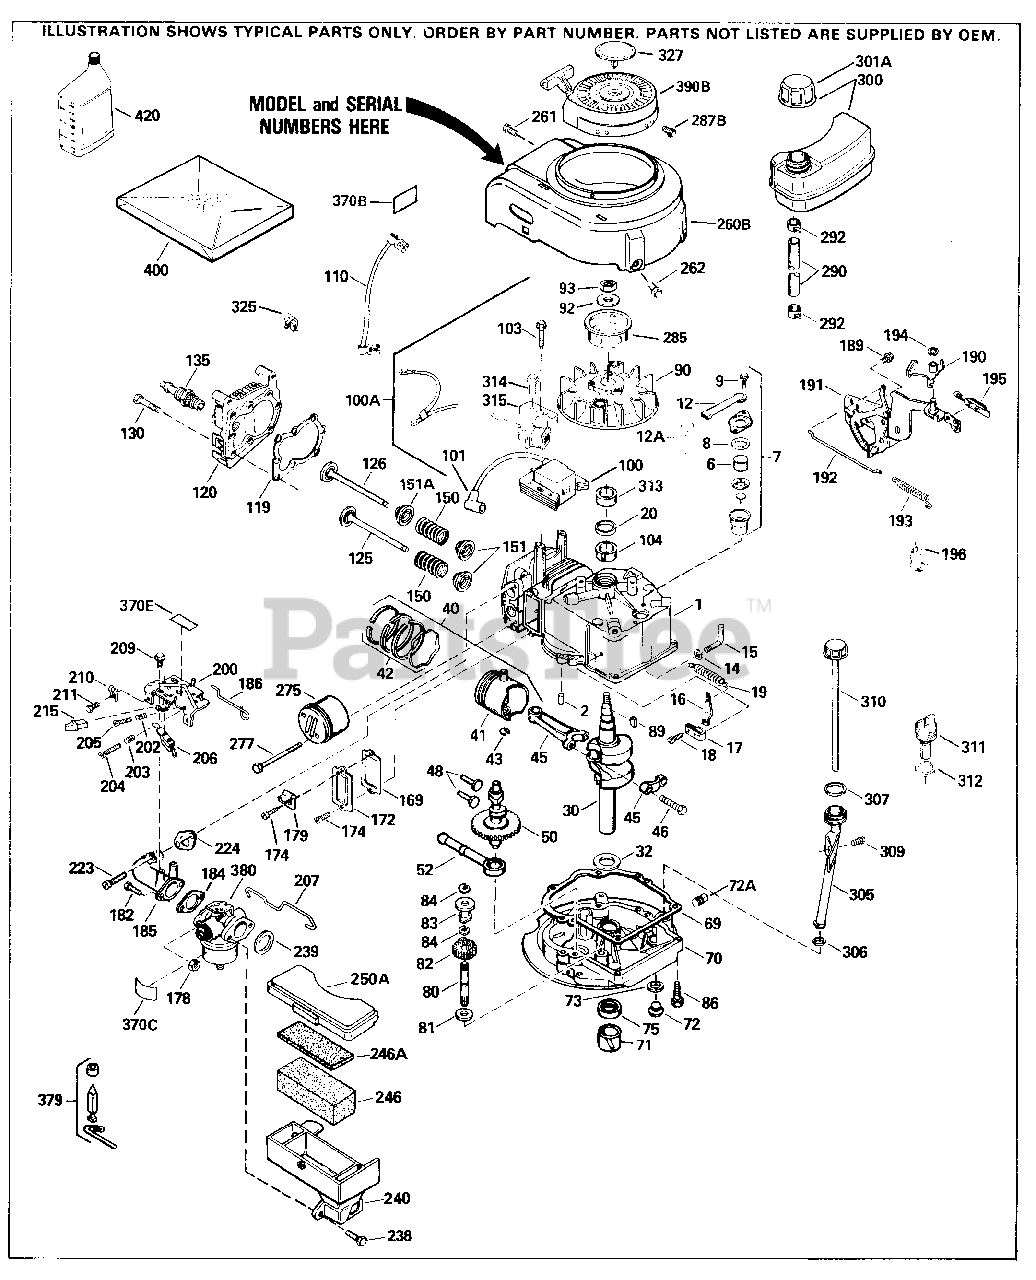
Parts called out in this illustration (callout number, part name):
1	"Cylinder (Incl. 2 & 20)
2	Dowel Pin
6	Breather Element
7	Breather Ass'y. (Incl. 6,8,9,12,12B)
8	* Breather Gasket
9	Screw, 10-24 x 9/16"
12	Breather Tube
12B	Breather Tube Elbow
14	Flat Washer
15	Governor Rod (Incl. 14)
16	Governor Lever
17	Governor Lever Clamp
18	Screw, 8-32 x 5/16"
19	Extension Spring
20	Oil Seal
30	Crankshaft
40	Piston, Pin & Ring Set (Std.)
40	Piston, Pin & Ring Set (.010" OS)
40	Piston, Pin & Ring Set (.020" OS)
41	Piston & Pin Ass'y. (Std.) (Incl. 43)
41	Piston & Pin Ass'y. (.010" OS) Incl. 43
41	Piston & Pin Ass'y. (.020" OS) Incl. 43
42	Ring Set (Std.)
42	Ring Set (.010" OS)
42	Ring Set (.020" OS)
43	Piston Pin Retaining Ring
45	Connecting Rod Ass'y. (Incl. 46)
46	Connecting Rod Bolt
48	Valve Lifter
50	Camshaft (BCR)
52	Oil Pump Ass'y.
69	* Mounting Flange Gasket
70	Mounting Flange (Incl. 72 thru 83)
72	Oil Drain Plug
73	Drain Plug Gasket
75	Oil Seal
80	Governor Shaft
82	Governor Gear Ass'y.(Incl. 81)
83	Governor Spool
86	Screw, 1/4-20 x 1-1/4"
89	Flywheel Key (also available in Packa ged Part #740007B)
90	Flywheel
92	Belleville Washer
93	Flywheel Nut
100	Solid State Ignition
101	Spark Plug Cover
103	Screw, Torx T-15, 10-24 x 1"
110	Ground Wire
119	* Cylinder Head Gasket
120	Cylinder Head
125	Exhaust Valve (Std.) (Incl. 151)
125	Exhaust Valve (1/32" OS) (Incl. 151)
126	Intake Valve (Std.) (Incl. 151)
126	Exhaust Valve (1/32" OS) (Incl. 151)
130	Screw, 5/16-18 x 1-1/2"
135	Resistor Spark Plug (RJ19LM) also ava ilable in Packaged Part #740081
150	Valve Spring
151	Valve Spring Cap
169	* Valve Cover Gasket
172	Valve Cover
174	Screw, 10-24 x 9/16"
178	Nut & Lock Washer 1/4-28
182	Screw, 1/4-28 x 7/8"
184	* Carburetor To Intake Pipe Gasket
185	Intake Pipe (Incl. 224)
186	Governor Link Spring
189	Screw, 1/4-20 x 3/8"
190	Brake Lever
191	S.E. Brake Bracket (Incl. 195)
192	Brake Control Link
193	Brake Spring
194	Retaining Ring
195	Terminal
207	Throttle Link
223	Screw, 1/4-20 x 1"
224	* Intake Pipe Gasket
238	Screw, 10-32 x 49/64"
239	* Air Cleaner Gasket
261	Screw, 10-24 x 9/16"
262	Screw, 1/4-20 x 1/2"
275	Muffler (Incl. 277)
277	Screw, 1/4-20 x 2-1/4"
285	Starter Cup
290	Fuel Line
292	Fuel Line Clamp
300	Fuel Tank (Incl. 292 & 301)
305	Oil Fill Tube
306	* "O"-Ring
307	"O" Ring
309	Screw, 10-32 x 1/2"
310	Dipstick
327	Starter Plug this)
380	Carburetor (Incl. 184)
400	* Gasket Set (Incl. items marked PK in notes) Incl. part #'s: 26756 (1), 272 34A (1), 33735 (1), 34265 (1), 34338 (1), 34690A (1), 35261 (1), 36477 (1)
999	Summer Maintenance Kit (incl. Oil, Sp ark Plug, Air Cleaners (2), & Ultra-F resh)
